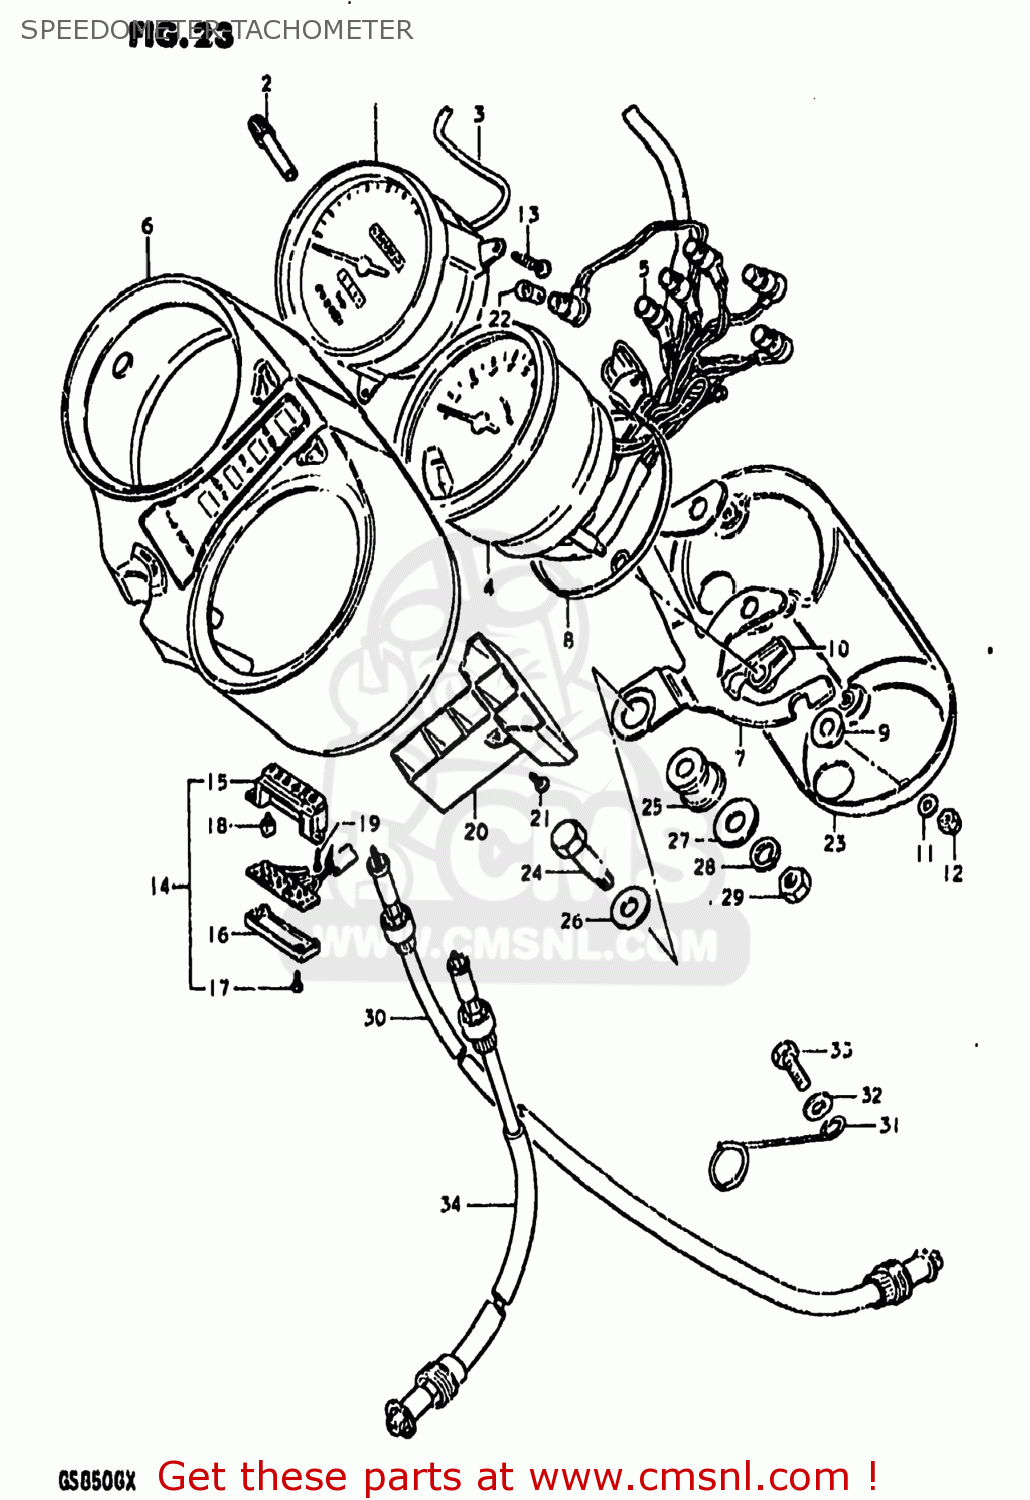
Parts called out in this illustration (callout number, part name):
1	SPEEDOMETER ASSEMBLY
2	KNOB
3	WIRE,LEAD
4	TACHOMETER
5	SOCKET,METER
6	CASE
7	BRACKET,COMBINATION METER
8	PLATE,METER,UNDER
9	CUSHION,METER (A)
10	CUSHION,METER (B)
11	WASHER
12	NUT
13	SCREW
14	INDICATOR ASSEMBLY,GEAR POSITION
15	CASE,GEAR INDICATOR
16	COVER,LWR
17	SCREW,GEAR INDICATOR
18	BULB(14V1.12W)
19	SCREW
20	CASE,PILOT BULB
21	SCREW
22	BULB(12V3.4W,STANLEY,A72A)
23	COVER,UNDER
24	BOLT
25	CUSHION,METER
26	WASHER
27	WASHER (8.5X29X1.6)
28	LOCK WASHER
29	NUT
30	CABLE ASSEMBLY,SPEEDOMETER
31	CLAMP,SPEEDOMETER CABLE
32	WASHER
33	BOLT, UPPER
34	CABLE ASSEMBLY,TACHOMETER
